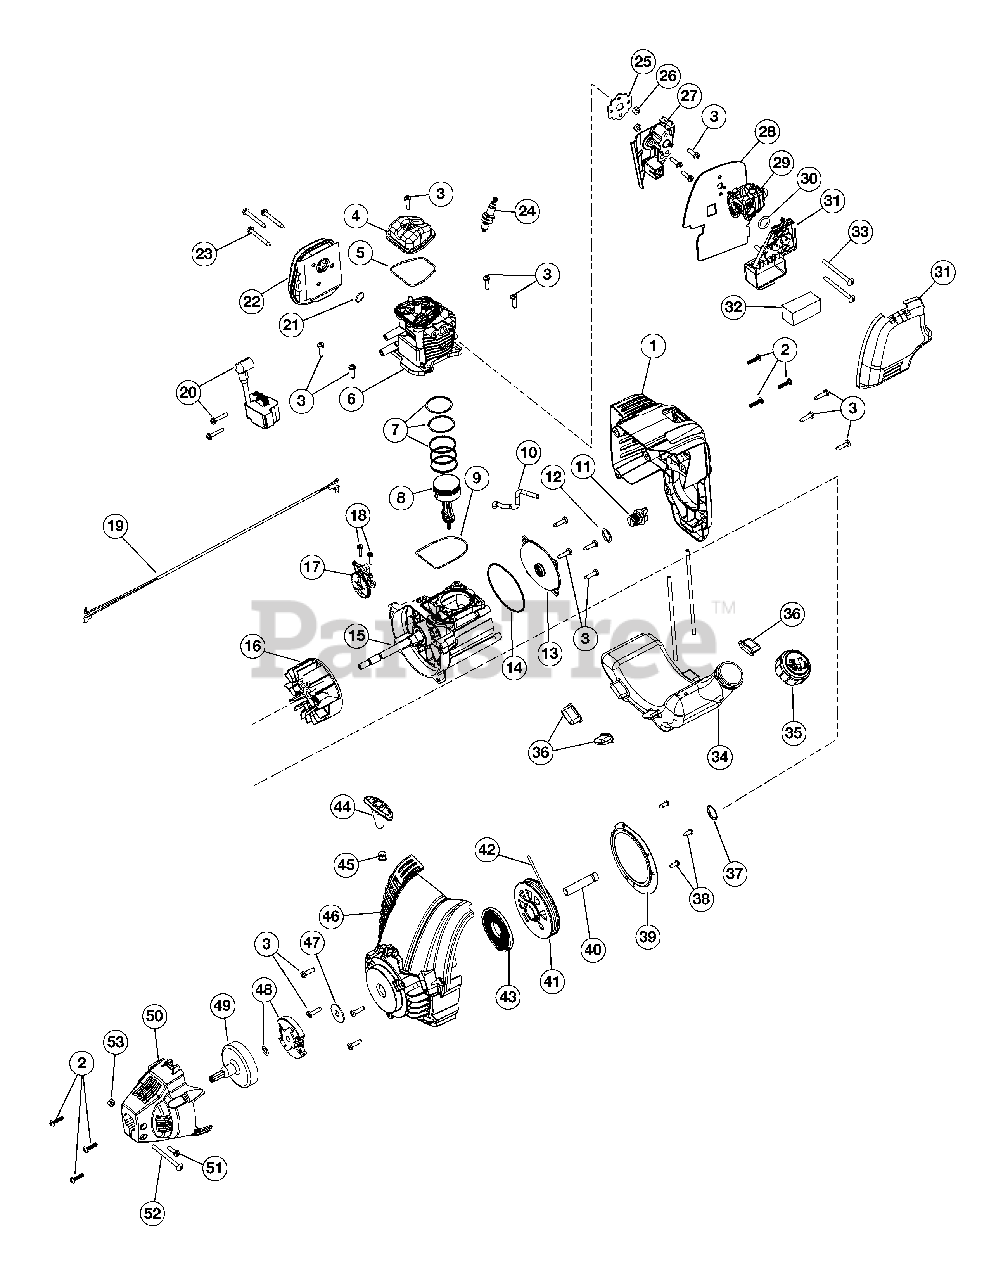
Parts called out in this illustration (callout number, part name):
1	Engine Cover Assembly
2	Cover Screw
3	Screw
4	Rocker Cover
5	Rocker Cover O-Ring
6	Cylinder Assembly
7	Piston Ring Assembly
8	Piston Assembly
9	Cylinder O-Ring
10	Breather Hose
11	Oil Plug
12	Oil Plug O-Ring
13	Crankcase Cover
14	Crankcase Cover O-ring
15	Crankcase Assembly
16	Flywheel Assembly
17	Cam Bracket Assembly
18	Cam Bracket Screw
19	Lead Wires
20	Module Assembly
21	Muffler Gasket
22	Muffler Assembly
23	Muffler Screw
24	Spark Plug
25	Insulator Gasket
26	Nut
28	Carburetor Gasket
29	Carburetor w/Primer
31	Air Cleaner Cover Assembly
32	Air Filter
34	Fuel Tank Assembly w/Fuel Lines
36	Fuel Tank Pads
38	Pressure Plate Screw
39	Pressure Plate
41	Starter Assembly
43	Recoil Spring
44	Handle
46	Starter Housing Assembly
48	Clutch & Clutch Washer
49	Clutch Drum
50	Clutch Cover
51	Anti-Rotation Screw
52	Clamp Screw
53	Nut
